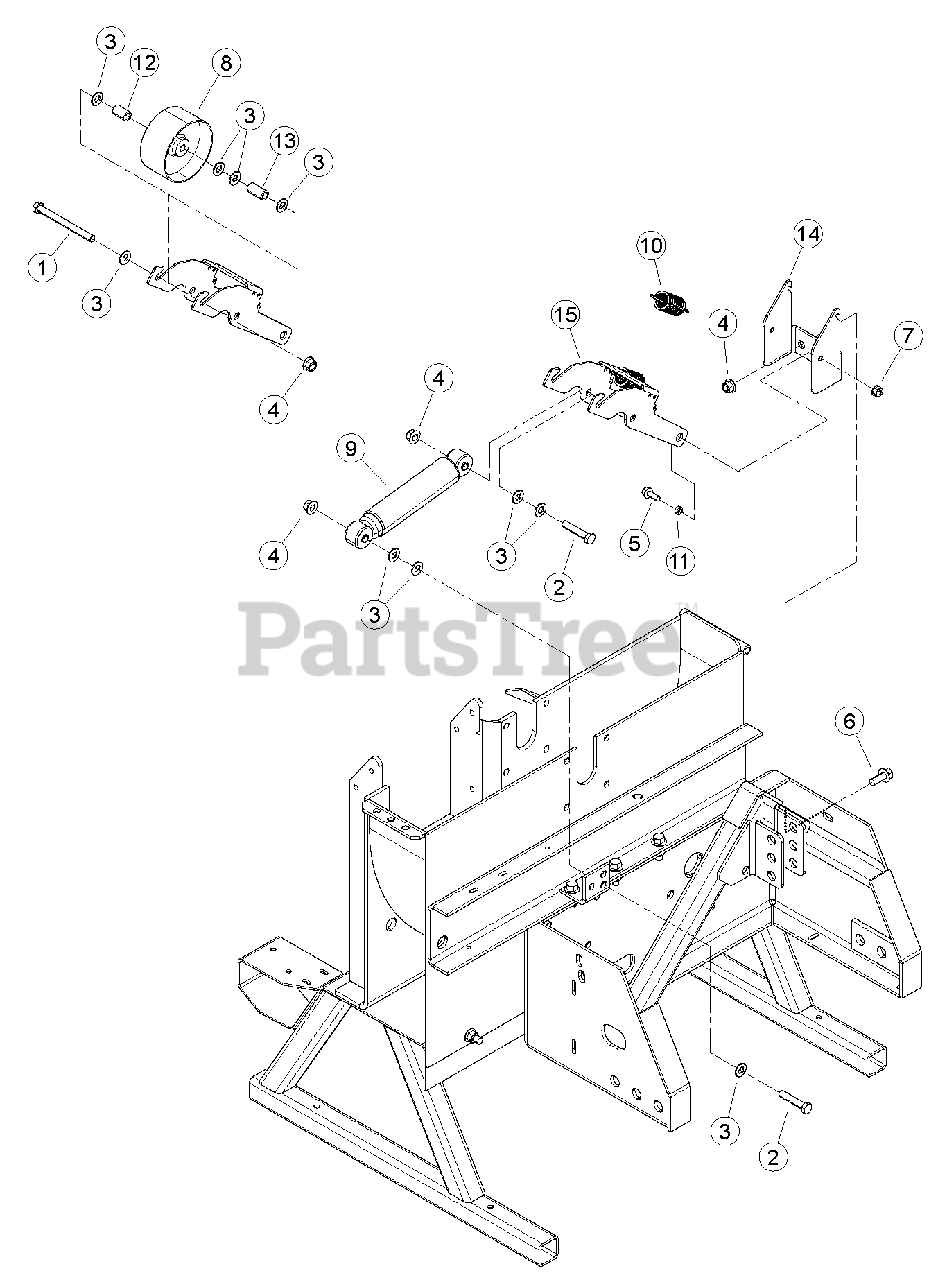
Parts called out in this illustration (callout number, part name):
1	BOLT, 1/2 X 5-1/2 HEX GR5 ZP
2	BOLT, 1/2 X 2-1/2 GR5 HEX CAP ZP
3	WASHER, 1/2 SAE FLAT
4	NUT, 1/2-13 NYLOCK FLANGE
5	BOLT, 3/8 X 1 FLANGE NC
6	BOLT, 1/2 -13 X 1-1/4 FLANGE NC
7	NUT, 3/8-16 NYLOCK FLANGE
8	PULLEY, IDLER 5 X 2.50"
9	ABSORBER, IDLER SHOCK
10	SPRING, 1.25 OD X 3.50 LG X .148 WD
11	SPACER, IDLER PIVOT
12	SPACER, .75 X 1.18
13	SPACER, .75 X 1.47
14	BRACKET, INSIDE IDLER MOUNTING
15	ARM, INSIDE IDLER
